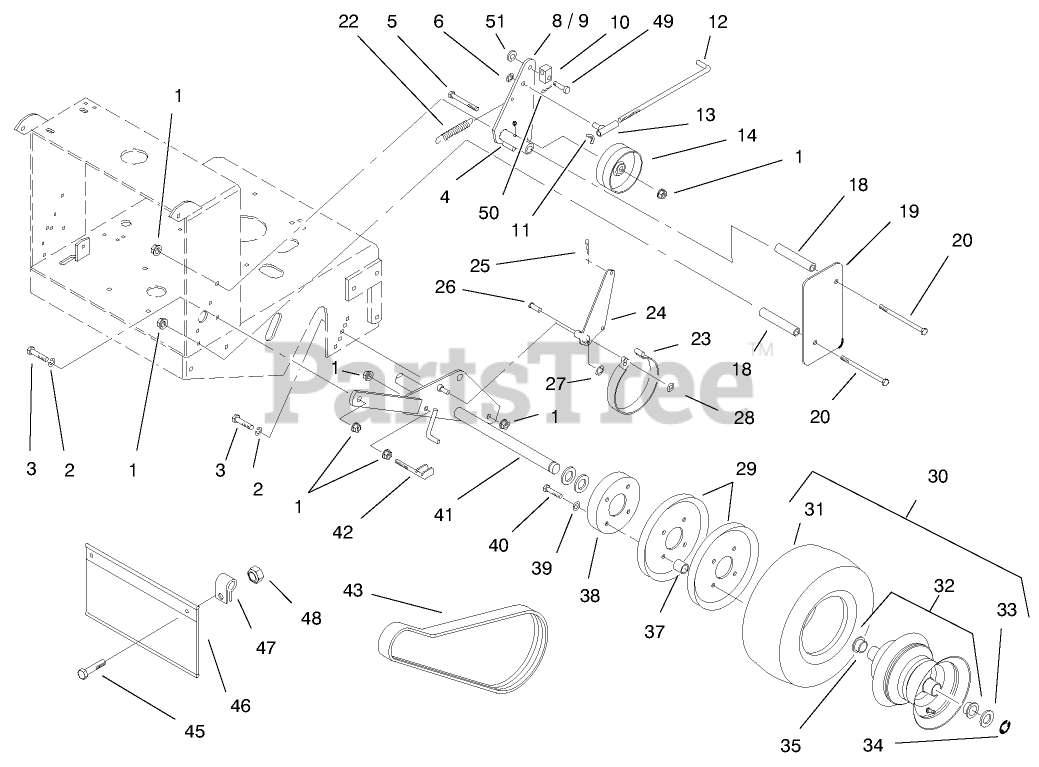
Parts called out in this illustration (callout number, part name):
1	NUT-FLANGE
2	Washer
3	SCREW-HH
4	FITTING-STRAIGHT
5	SCREW-HH
6	Ring
8	Idler Arm ASM LH
9	Idler Arm ASM RH
10	FITTING-ROD
11	Wingnut
12	Brake Rod
13	Swivel
14	Idler-Wheel Drive
18	Idler
19	Shield
20	SCREW-HH
22	Spring-Extension
23	Band-Brake
24	Brake Arm ASM
25	PIN-COTTER
26	Pin
27	Ring-Snap
28	Nut
29	Sheave
30	WHEEL AND TIRE ASM
31	Tire
32	Assembly-Wheel
33	Spacer
33	Spacer-18 GA
34	Ring,Snap E
35	Bearing
37	Spacer
38	Drum-Brake
39	WASHER-LOCK
40	SCREW-HH
41	Axle ASM
42	Scraper
43	Belt-Drive
45	SCREW-HH
46	Shield-Trailing
47	CLAMP-R
48	NUT-LOCK NI
49	PIN-CLEVIS
50	PIN-COTTER
51	WASHER-PLAIN
